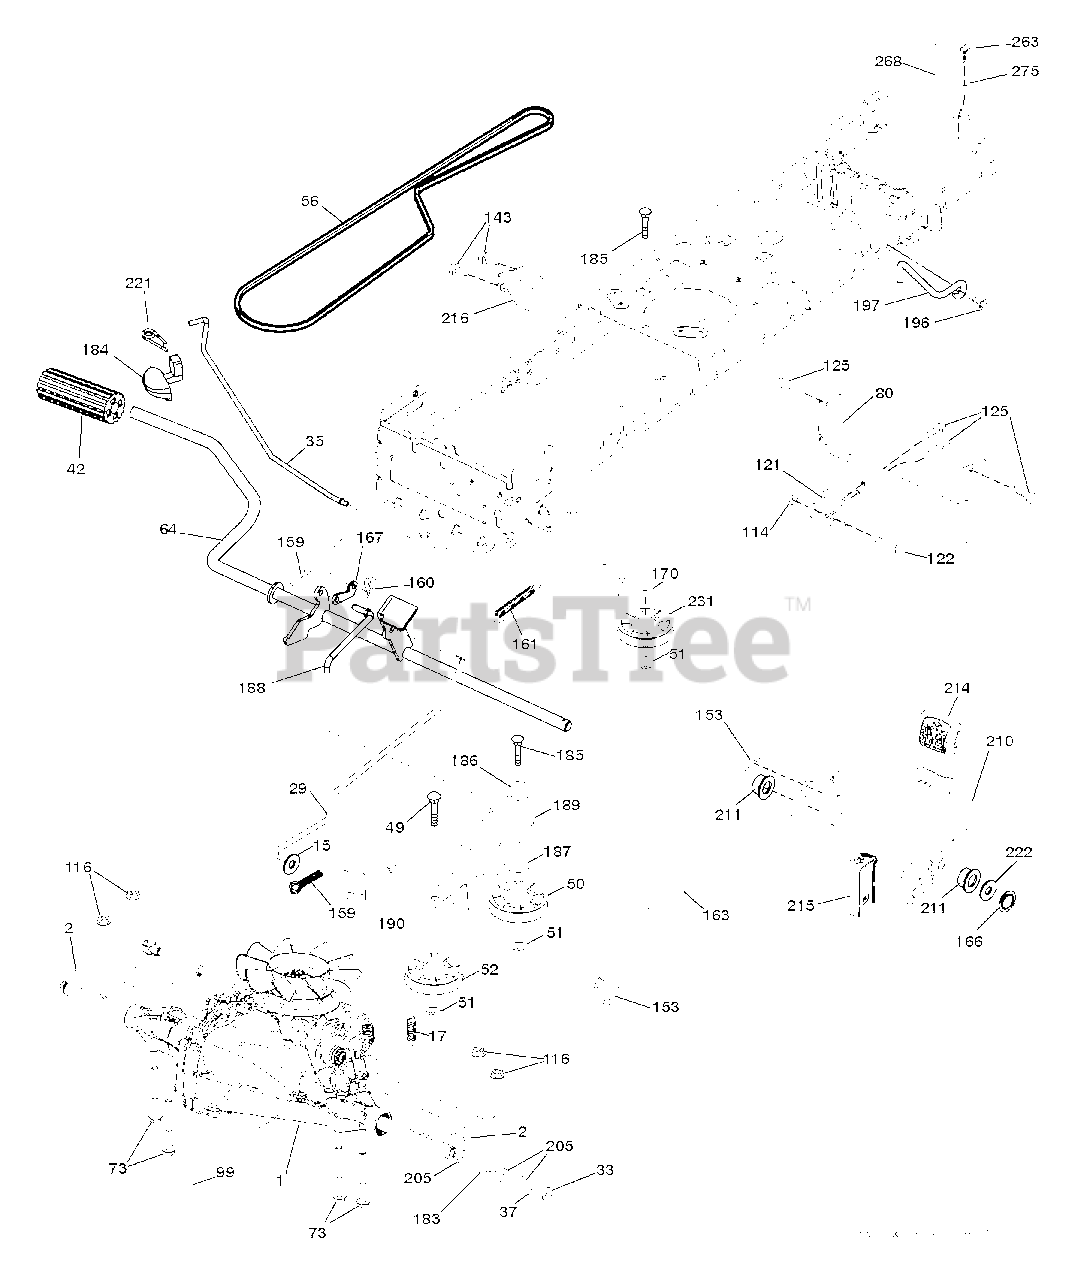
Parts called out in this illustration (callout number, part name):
2	SQUARE KEY
17	SPRING.BRAKE.HG3000/3500
29	ROD BRAKE
33	E-RING LT
35	ROD, BRAKE, PARK
42	PEDAL COVER T
49	BOLT
50	IDLER.FLAT.910.OFFSET
51	NUT LOCK FLG 3/8-16 UNC
52	IDLER.V-GROOVE.910.OFFSET
64	SHAFT.ASM.PEDAL.BRK.CNTR
73	BOLT HEX 5/16-18 GR 5
80	STRAP.TORQUE.FS.T2
99	ROD.ASM.BYPASS.SPRING.T2.FS
114	NUT.71038.31-18.HEX.NYLOCK
116	NUT LOCK HEX FLANGE 5/16-18
121	BRACKET STRAP TORQUE
122	BOLT.5/16-18X2.5
125	SCREW
153	RETAINER M
159	COTTER PIN
160	RETAINER CLIP
161	SPRING, RETURN LT
163	ROD.CONTROL.PCH.T2.TEX
166	NUT.PUSH.625
167	LATCH.BRAKE.SPRING
170	KEEPER.CENTER SPAN.1.688
183	SPACER, AXLE PVST
184	HANDLE.PARKING.BRK.PRED.LT.RED
186	SPACER.RETAINER
187	WASHER 12/32X2X10GA
188	LINK.CLUTCH.GROUND.DRIVE
189	BELLCRANK.GROUND.DRIVE.TEX.
190	KEEPER.BELLCRANK.DRIVE
196	SCREW 3/8-16X1
197	LINK.CLUTCH.ANIT-ROTAT
210	ROCKER.ASM.PEDAL.CONTR
211	BEARING.NYLON
214	PAD PEDAL FORWARD
215	PEDAL.REVERSE.TEX.GT.4
216	BRACKET.PULLEY.IDLER.W/TEX
221	RETAINER.SPRING.CLIP.H
222	WASHER 21/32 X 1-1/4 X 10 GA.
231	IDLER.V-GROOVE.1.688.OFFSET
263	SCREW, 3/8-16X3/4
275	WASHER
